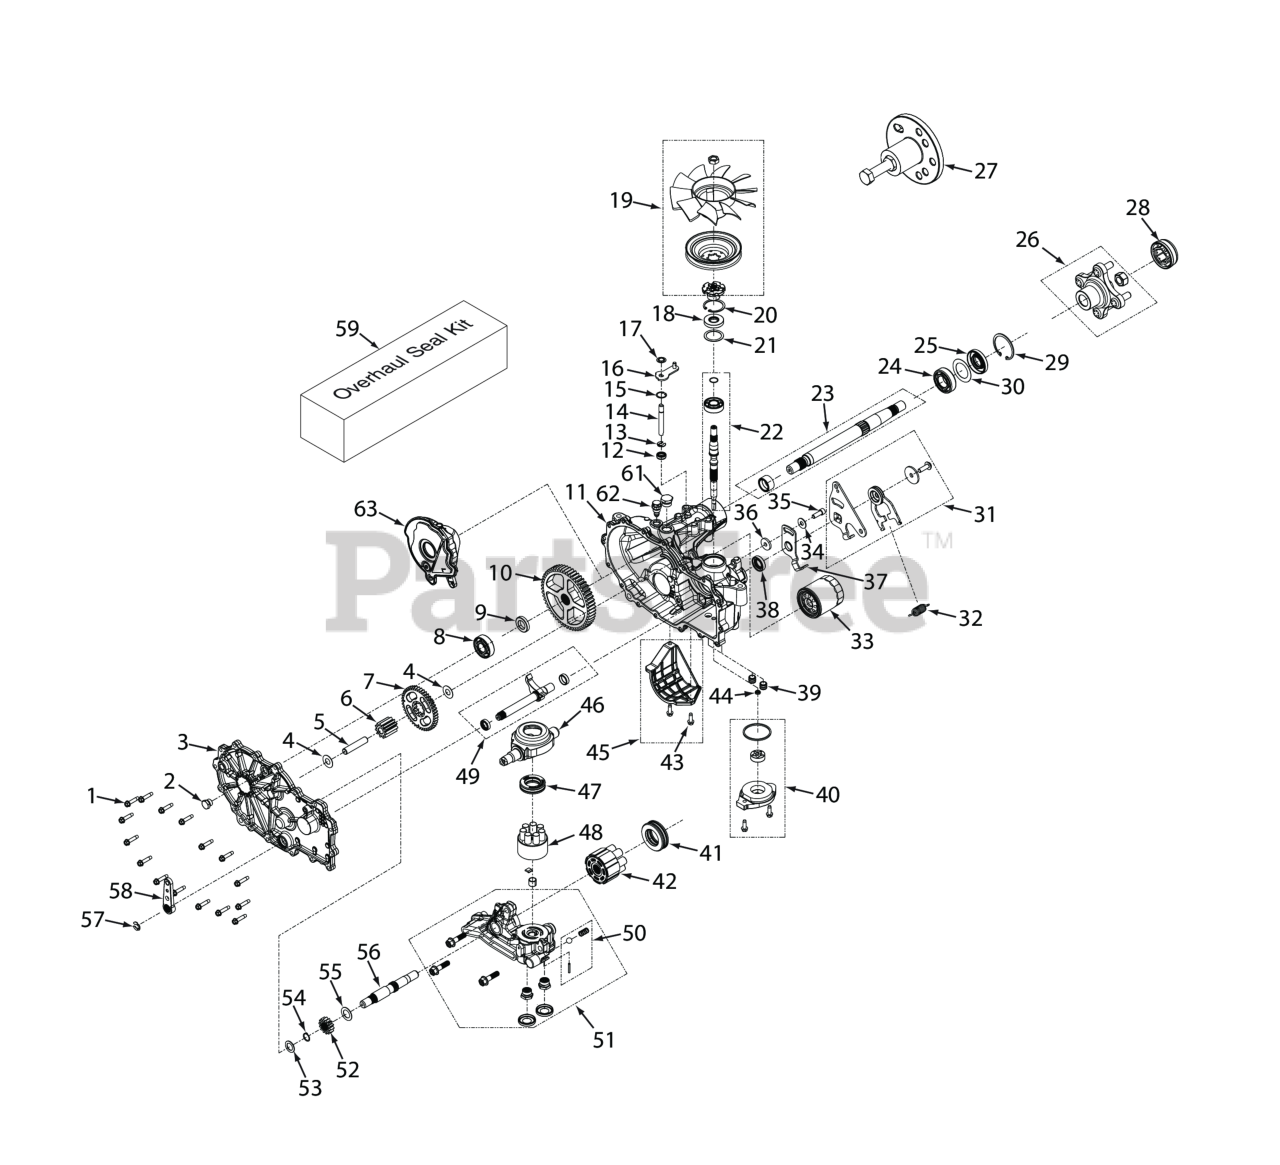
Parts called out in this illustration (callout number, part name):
1	Bolt, Hex Head 1/4-20 x 1-1/8"
2	Plug, External Hex Vent 9/16-18
3	Kit, Side Cover LH
4	Washer, .5 x 1.0 x .03
5	Jackshaft Pin
6	Gear, 11T
7	Gear, 45T
8	Kit, Bearing
9	Spacer, .750 x 1.320 x .257
10	Gear, 54T
11	Kit, Main Housing LH, Charge, Control
12	Seal, Lip, .375 x .75 x .25
13	Ring, .Retaining .375 External
14	Rod, By-Pass
15	R i n g , Retaining .750 Internal
16	Arm, Bypass (LH)
17	Ring, Retainging .375 External
18	Seal, Lip 17 x 40 x 7
19	Kit, Fan/Pulley
20	R i n g , Retaining 2.06 Internal
21	Washer, 1.23 x 1.56 x .04
22	Kit, Input Shaft
23	Kit, Shaft, Axle
24	Bearing, Ball 1.0 x 52 x 15 Open
25	Seal, Lip TC4 1.0 x 2.06 x .38
26	Hub, 4-Bolt
27	Kit, Hub Puller
28	Cap, Axle
29	R i n g , Retaining 2.06 Internal
30	Spacer, 1.355 x 2.035 x .021
31	Kit, RTN Bi-Directional (Right Side)
32	Spring, Extension, RTN - 44lbs
33	Filter, Oil
34	Washer, 7/16 x 7/8 OD x .06 HT
35	Bolt, Hex Head Cap Screw 5/16-24 x 1" Patch
36	Spacer, .32 ID x 1.005 OD x .1495 Thk
37	Arm, Neutral (Left Side)
38	Seal, Lip 18 x 32 x 7
39	Tube, Charge Triple O-ring
40	Kit, Charge Pump
41	Thrust Ball Bearing Assembly
42	Kit, 16cc Cylinder Block Assembly (steam
43	Bolt, 1/4-20 x 3/4"
44	Kit, Gerotor Seal
45	Kit, Filter Guard (LH)
46	Trunnion, Swashplate
47	Ball Thrust Bearing
48	Kit, Cylinder Block
49	Kit, Inboard, RH Rot B / LH Rot A (LH)
50	Kit, Charge Relief
51	Kit, Charge Relief
52	Washer, Flat, .71 x 1.16 x .04
53	Washer, HT .62 ID x 1.0 OD x .05 Thick
54	Ring, Retaining .625
55	Washer, .72 x 1.16 x .04
56	Shaft, Motor
57	Ring, Retaining External .375"
58	Handle, Brake
59	Kit, Seal (ZT-2800)
61	Plug, 3/4-16
62	Fitting 9 /16 - 18, Breather
63	Expansion Tank, Internal LH
